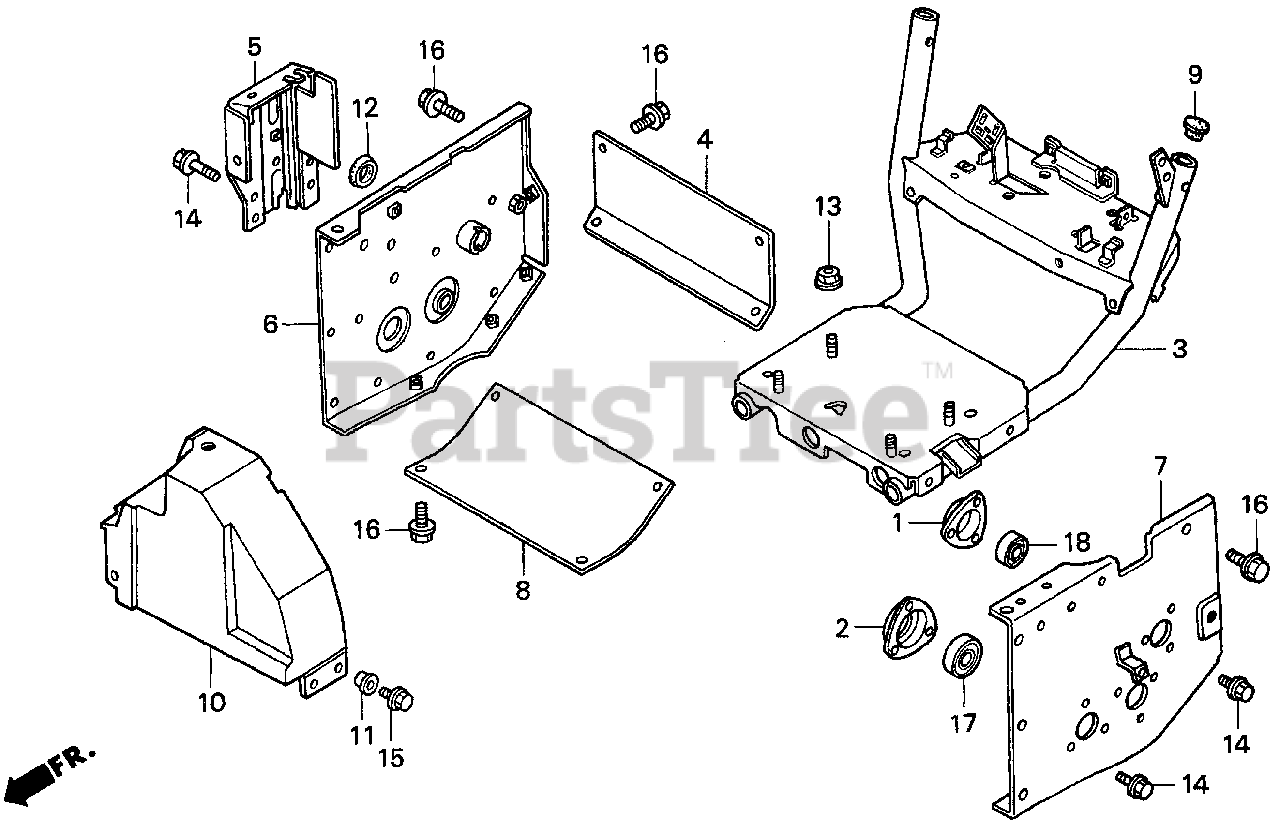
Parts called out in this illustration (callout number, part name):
1	HOLDER, BEARING
2	HOLDER, WHEEL SHAFT BEARING
3	BED, ENGINE
4	STAY, ENGINE BED
5	HOLDER, WIRE
6	STAY, R. ENGINE BED
7	STAY, L. ENGINE BED
8	STAY, ENGINE BED (B)
9	CAP, HANDLE (LOWER)
10	COVER, BELT
11	WASHER, CHAIN CASE SETTING
12	COVER, DUST (28MM)
13	NUT, FLANGE (8MM)
14	BOLT, FLANGE (6X12)
15	BOLT, FLANGE (6X14)
16	BOLT, FLANGE (8X12)
17	BEARING, RADIAL BALL (6004UU)
18	BEARING, RADIAL BALL (6201UU)
